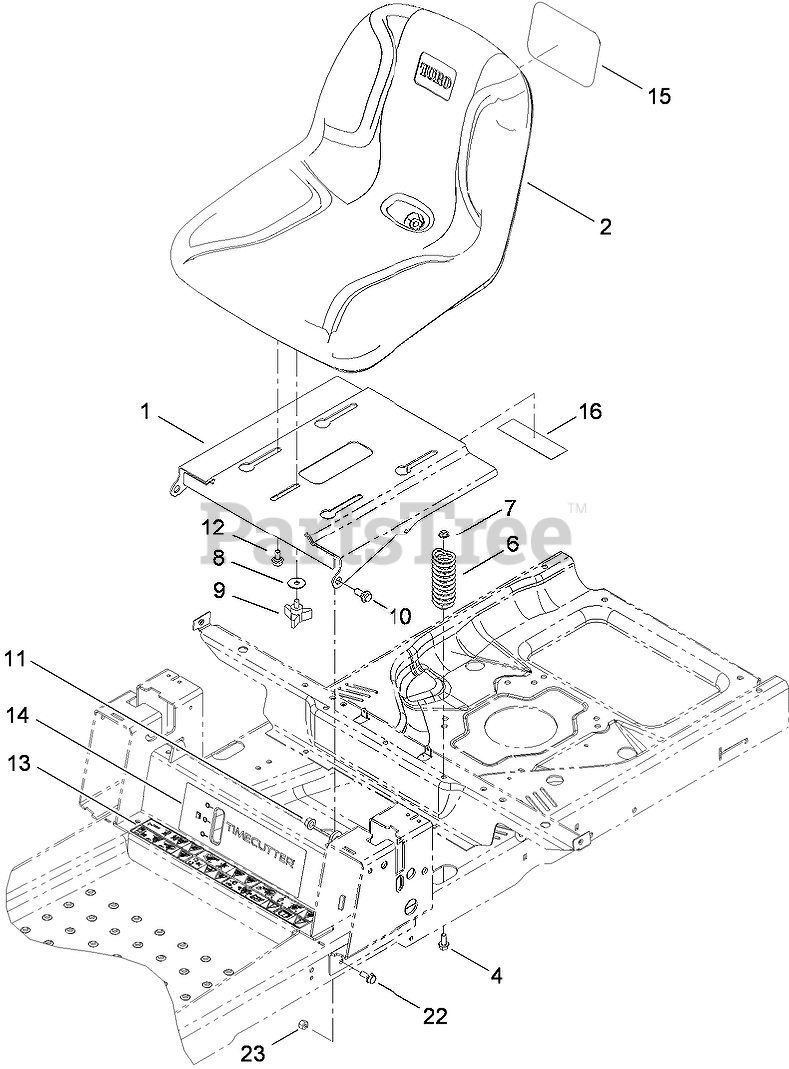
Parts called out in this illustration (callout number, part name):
1	BASE-SEAT
2	SEAT-15 INCH
4	SCREW-HHF
6	SPRING-COMPRESSION
7	NUT-HF, NI
8	WASHER-PIVOT
10	BOLT-SHOULDER
11	NUT-HF
12	BOLT-SHOULDER
13	DECAL-DANGER
15	DECAL
16	DECAL-SERVICE, CE
22	SCREW-HHF
23	NUT-LOCK, NI
